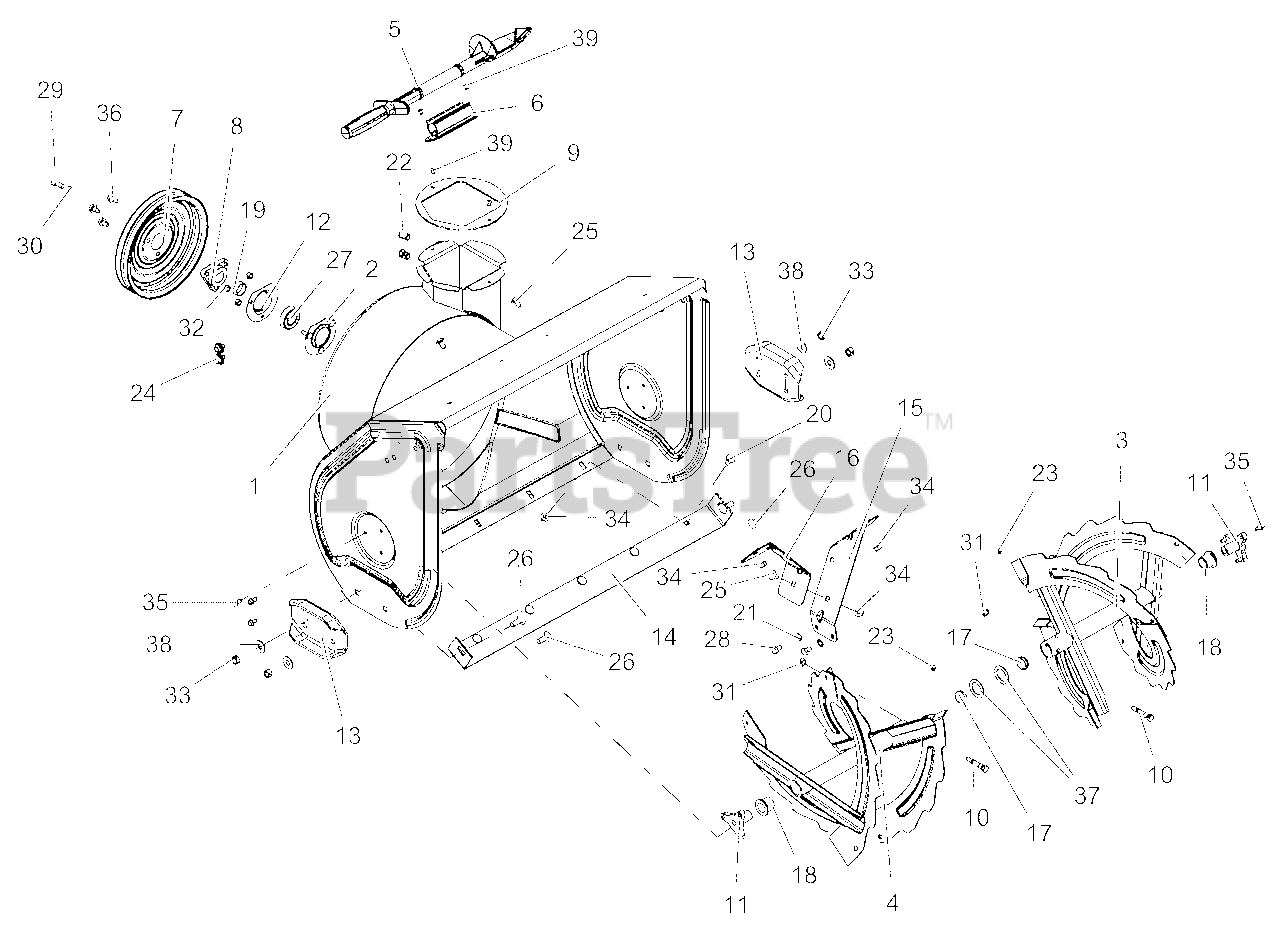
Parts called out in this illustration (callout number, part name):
1	BLOWER HOUSING, 28"
2	BEARING FLANGE
3	RAKE, LH W/ZERK - 28"
4	RAKE, RH W/ZERK - 28"
5	DEVICE, SNOW CLEAN OUT
6	MOUNT, SNOW CLEAN OUT
7	PULLEY, SPIN FORM DUAL GROOVE
8	PULLEY HUB, D-BORE .87 DELUXE
9	BAFFLE, DISCHARGE NECK
10	SHEAR BOLT SERVICE ASSEMBLY
11	SUPPORT, RAKE BUSHING
12	BEARING FLANGE
13	SKID SHOE, REVERSIBLE - ORANGE
14	BLADE, SCRAPER - 28"
15	BRACKET, GEARCASE SUPPORT - LH
16	BRACKET, GEARCASE SUPPORT - RH
17	PLUG, RAKE TUBE
18	BSHG-FLG, NY.778 ID X 1.018 OD
19	BSHG-SPCR .895IDX1.065ODX.353
20	BOLT, MODIFIED HEAD CARRIAGE
21	@WSHR-LK-EXT.326X.599X.031YWZC
22	NUT, THREADED INSERT .38-16
23	ZERK,FITTING .25X.125 DRIVE IN
24	SCR-TAP.31-18X.50 HWH TR YWZ
25	BLT-RDHDSQSHNK.31-18X.62 YZ-LK
26	@BLT-RDHDSHSQNK.38-16X1.0 G5YZ
27	BRG-BALL .876 X 1.750 X .50
28	@BLT-HEX .31-18X.50 GR5 YWZC
29	BLT-HEX .31-24X.75 YWZC GR5
30	WSHR-LK .312X.097 HVY YWZC
31	@NUT-LK-CTR .31-18 YWZC
32	@NUT-LK-CTR .25-20 YWZC
33	@NUT-LK-CTR .38-16 YWZC
34	@NUT-LK-TOP-FLG .31-18 YWZC
35	SCR-TAP .25-20X.50 HWH TR YWZ
36	@SCR-TAP .31-18X.50 HWH TR YWZ
37	WSHR-FL-STL 1.010X1.505X.062YZ
38	@WSHR-FL-STL.438X1.00X.083 YWZ
39	RVT-POP .187 YZ
